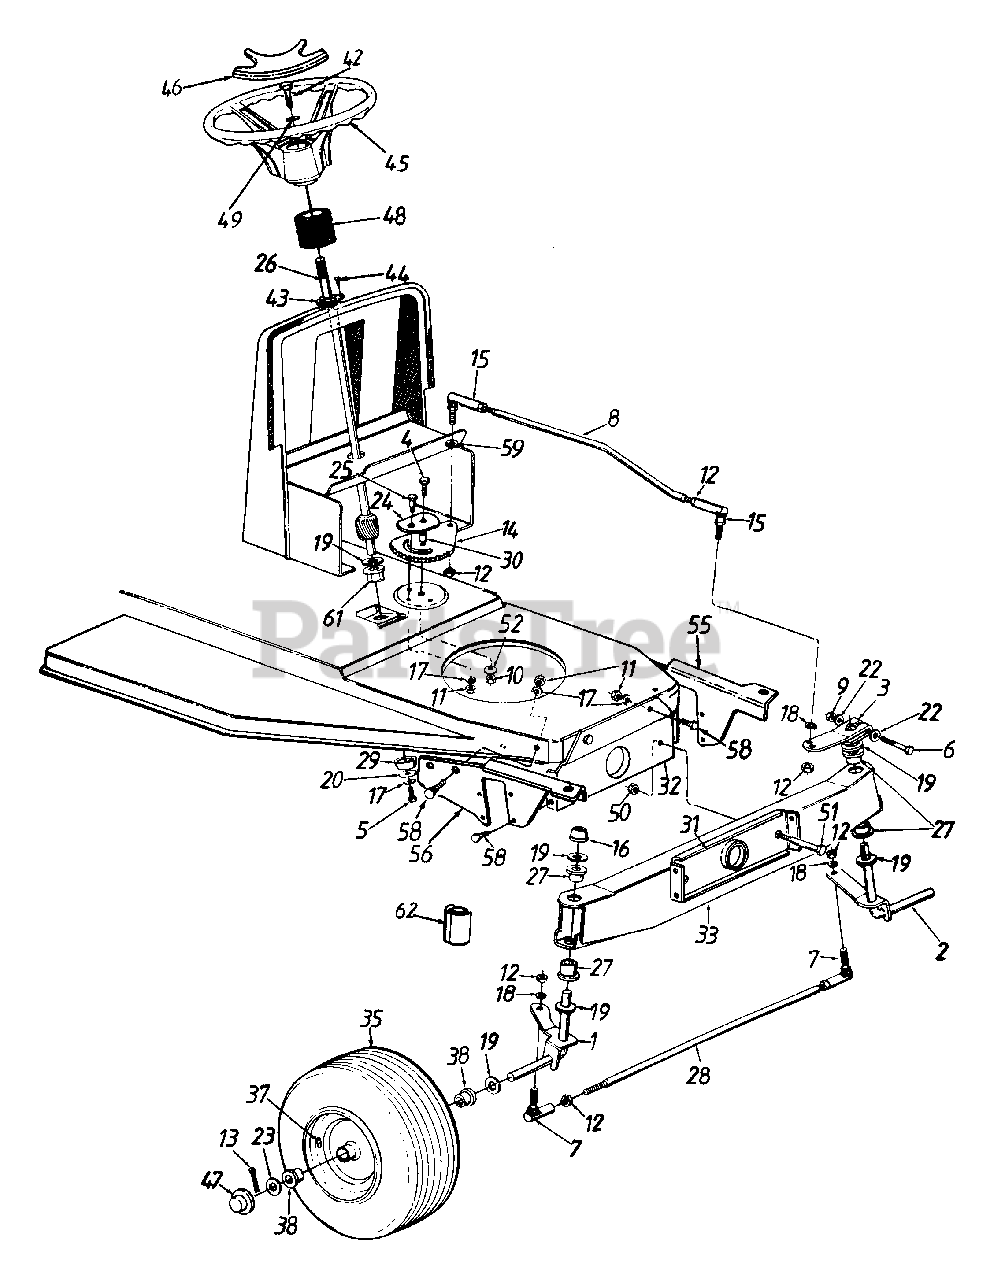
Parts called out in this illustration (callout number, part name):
4	Hex Bolt 3/8-24 x 1" Lg.
5	Hex Bolt 5/16-18 x .62" (Spec)
6	Hex Bolt 5/16-24 x 2" Lg.
7	Ball Joint 3/8-24 Thd.
8	Steering Drag Link
9	Hex L-Nut 5/16-24 Thd.
10	Hex Nut 3/8-24 Thd.
11	Hex Nut 5/16-18 Thd. (Gr. 5)
12	Hex Jam Nut 3/8-24 Thd.
13	Cotter Pin 1/8 Dia.
14	Steering Gear Segment
15	Drag Link Ball Joint 3/8-24 Thd.
17	L-Wash. 5/16" I.D.
18	L-Wash. 3/8" I.D.
19	Fl-Wash. .64" I.D. x 1.24"
20	Fl-Wash. .340" I.D. x 1.125"
22	Spr. Wash. .32" I.D. x .62"
23	Fl-Wash. .635" I.D. x 1.585"
24	Retainer Plate
25	Shld. Bolt .437" Dia. x .350"
26	Steering Shaft
27	Hex Flange Brg. .632" I.D.
29	Spacer .985" I.D.
30	Spacer .380" I.D.
38	Bearing
42	Hex L-Bolt 5/16-18 x 1" Lg. (Gr. 5)
43	Steering Column Brg.
44	Cr-Sunk Scr. #10 x 5/8" Lg.
45	Steering Wheel
46	Steering Wheel Cap
47	Hub Cap
48	Bellow Steering Column
49	Bell-Wash. .345" I.D. x .88"
50	Hex Nut 3/8-16 Thd.
51	Shld. Bolt 1/2" Dia. x 2.04"
52	Bell-Wash. .39" x 1.38" O.D.
59	L-Wash. 3/8" I.D. (H.D.)
61	Hex Flange Brg. .634" Dia.
62	Axle Cap
